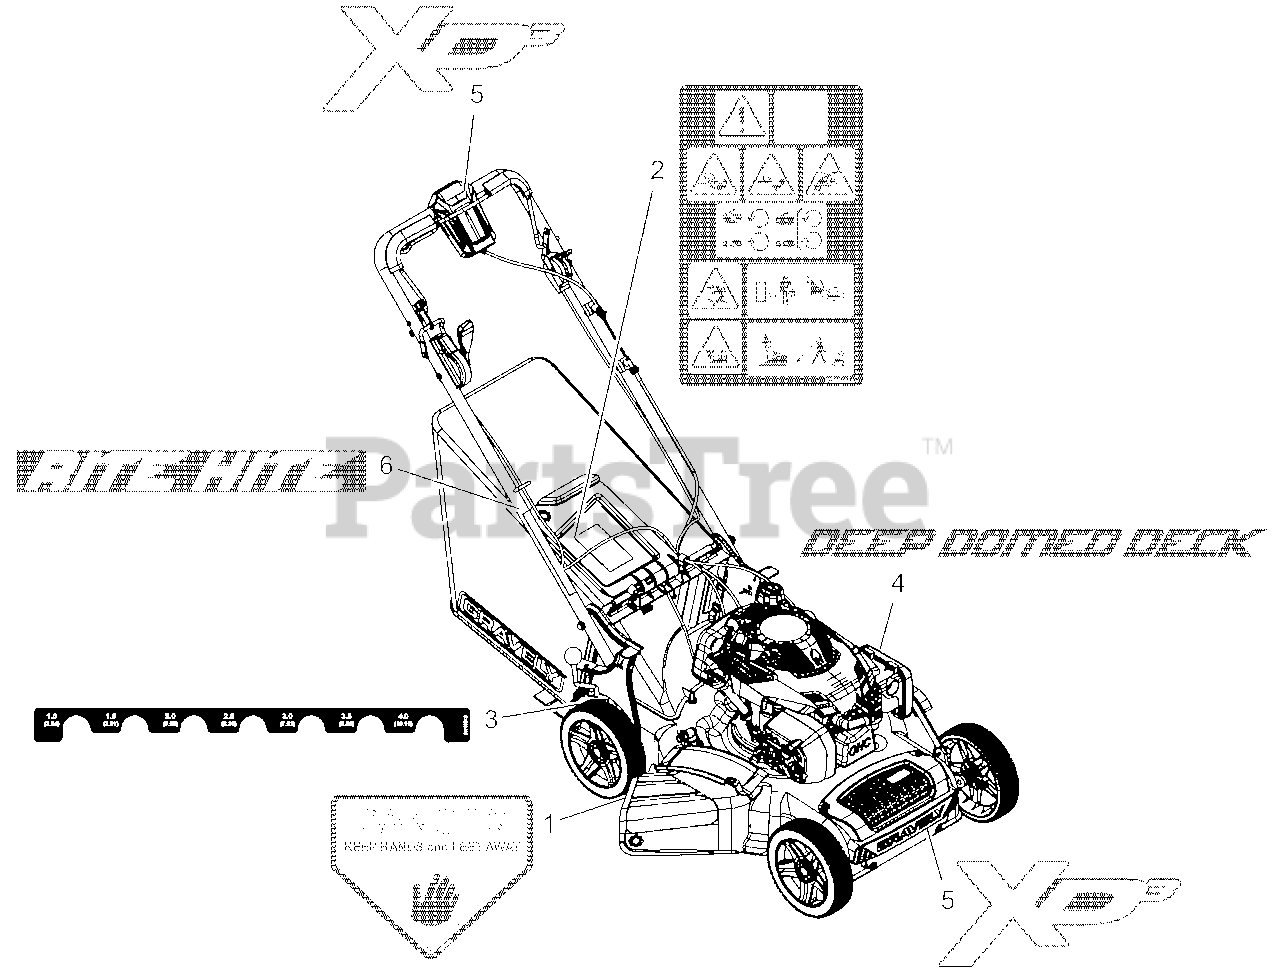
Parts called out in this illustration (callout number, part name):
1	DECAL, DANGER
2	DECAL, MAIN SAFETY WAW LM
3	DECAL, HOC
4	DECAL, DEEP DOME DECK
5	DECAL, GRAVELY XD3 STYLE
6	DECAL, RITE HITE
